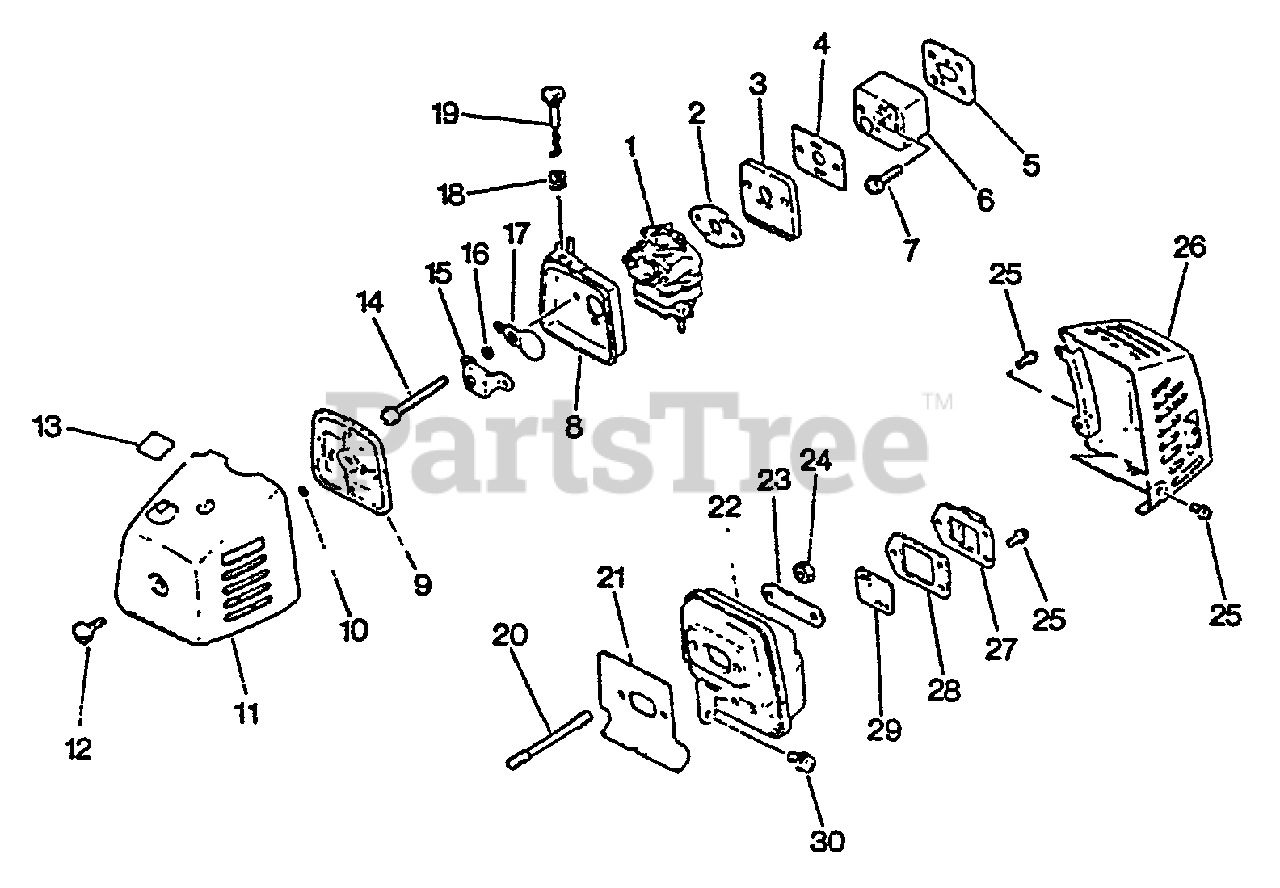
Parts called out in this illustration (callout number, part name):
1	CARBURETOR
2	GASKET, INTAKE
3	PLATE
4	GASKET, INTAKE
5	GASKET, INTAKE
6	INSULATOR, INTAKE
7	SCREW - 5X22
8	CASE, AIR FILTER
9	FILTER, AIR
10	O-RING - 4
11	COVER, AIR FILTER
13	LABEL - CHOKE
14	SCREW - 5X50
15	PLATE, PREVENT
16	WASHER - 5
17	SHUTTER, CHOKE
19	ROD, CHOKE
20	STUD - 5X60
21	GASKET, EXHAUST
22	MUFFLER
24	LOCKNUT - 5
25	SCREW - 4X8
26	COVER, EXHAUST
27	GUIDE, EXHAUST
28	GASKET, EXHAUST
29	SCREEN, SPARK ARRESTOR
30	SCREW - 5X10
